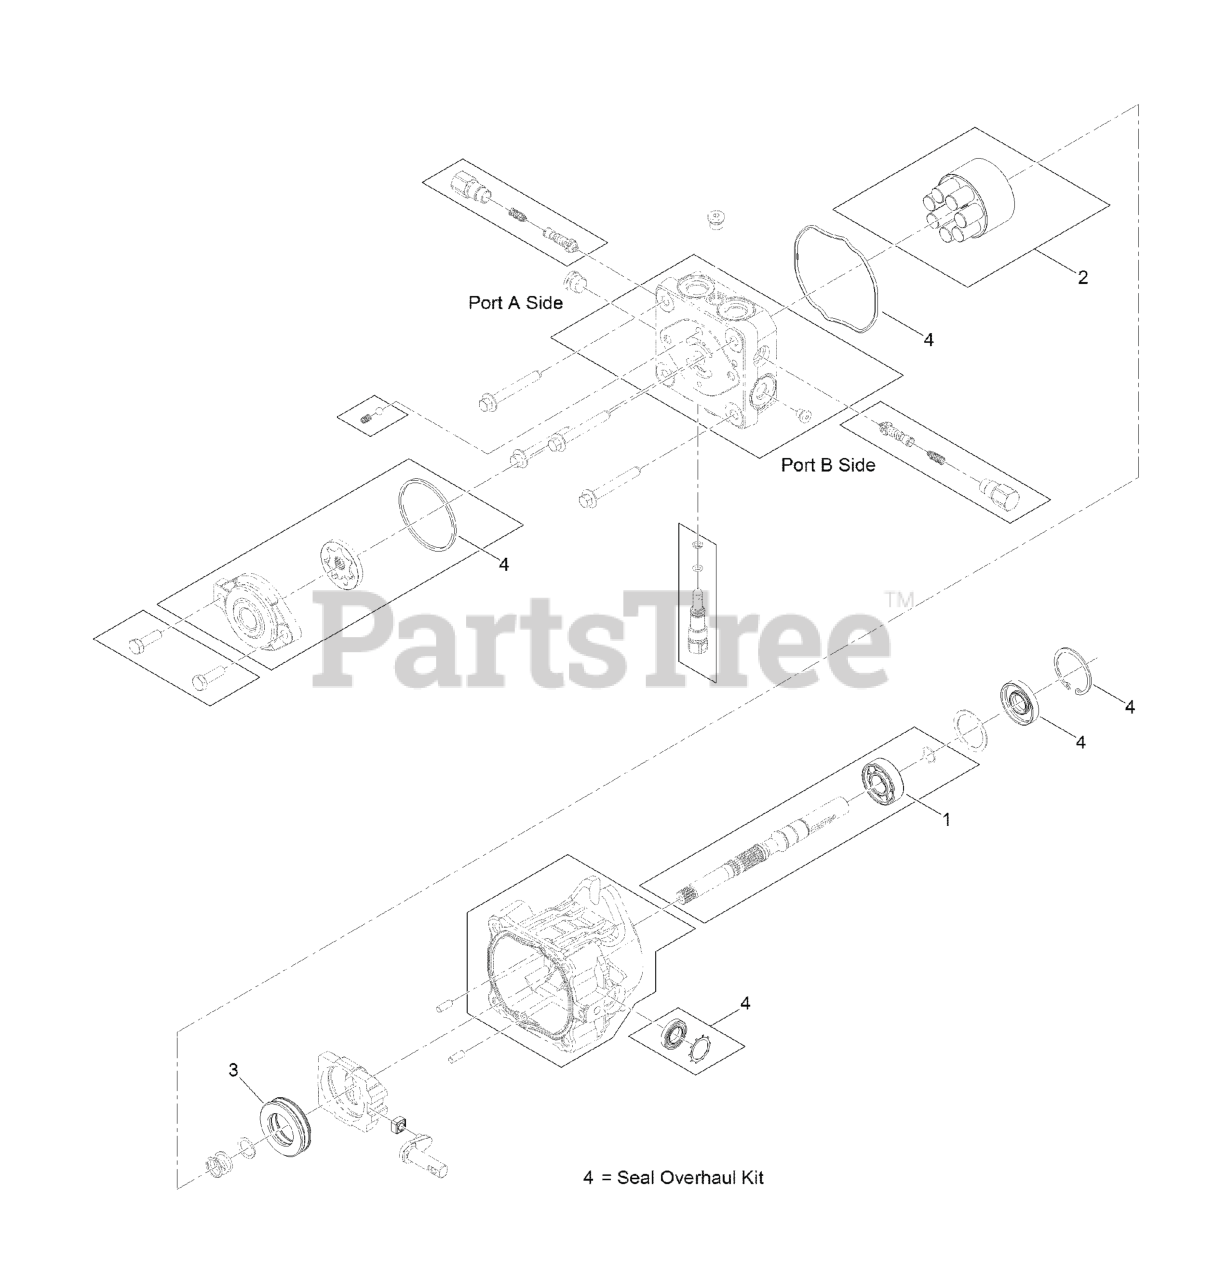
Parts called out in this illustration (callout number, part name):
1	BEARING-BALL
2	CYLINDER BLOCK KIT
3	BEARING-THRUST, PLASTIC C
4	SEAL OVERHAUL KIT
